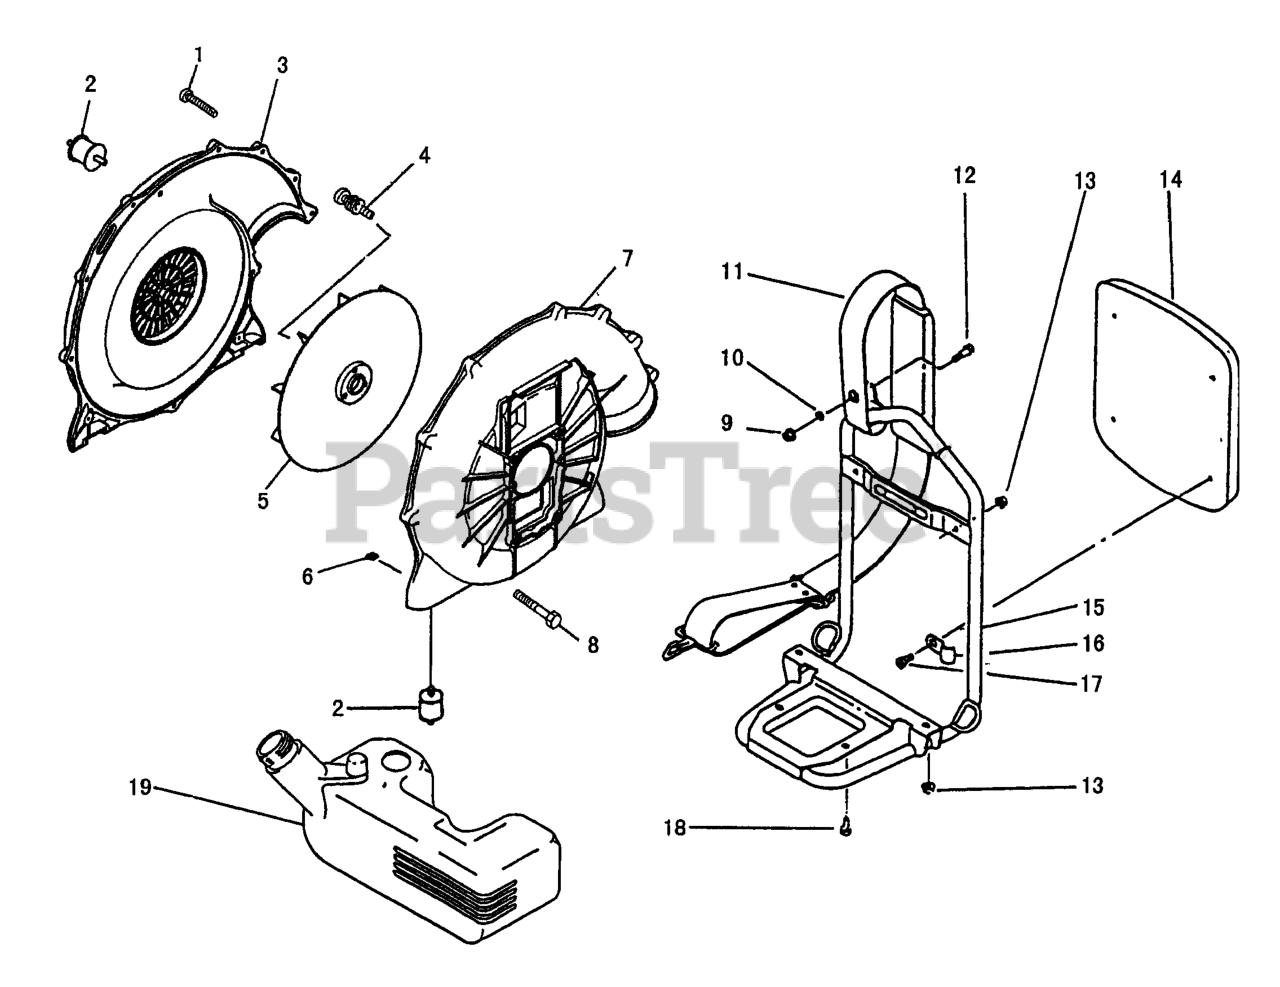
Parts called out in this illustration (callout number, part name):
1	Tapping Screw (M5x30)
2	VIBRATION DAMPER
4	BOLT
6	NUT
7	FANCASE-REAR
8	BOLT
9	NUT
10	WASHER
11	Shoulder Band
12	TRUSS SCREW
13	Flange Nut (M6)
14	KNAPSACK PAD
16	PAD FITTING
18	SCREW 6X10MM 374L0610
